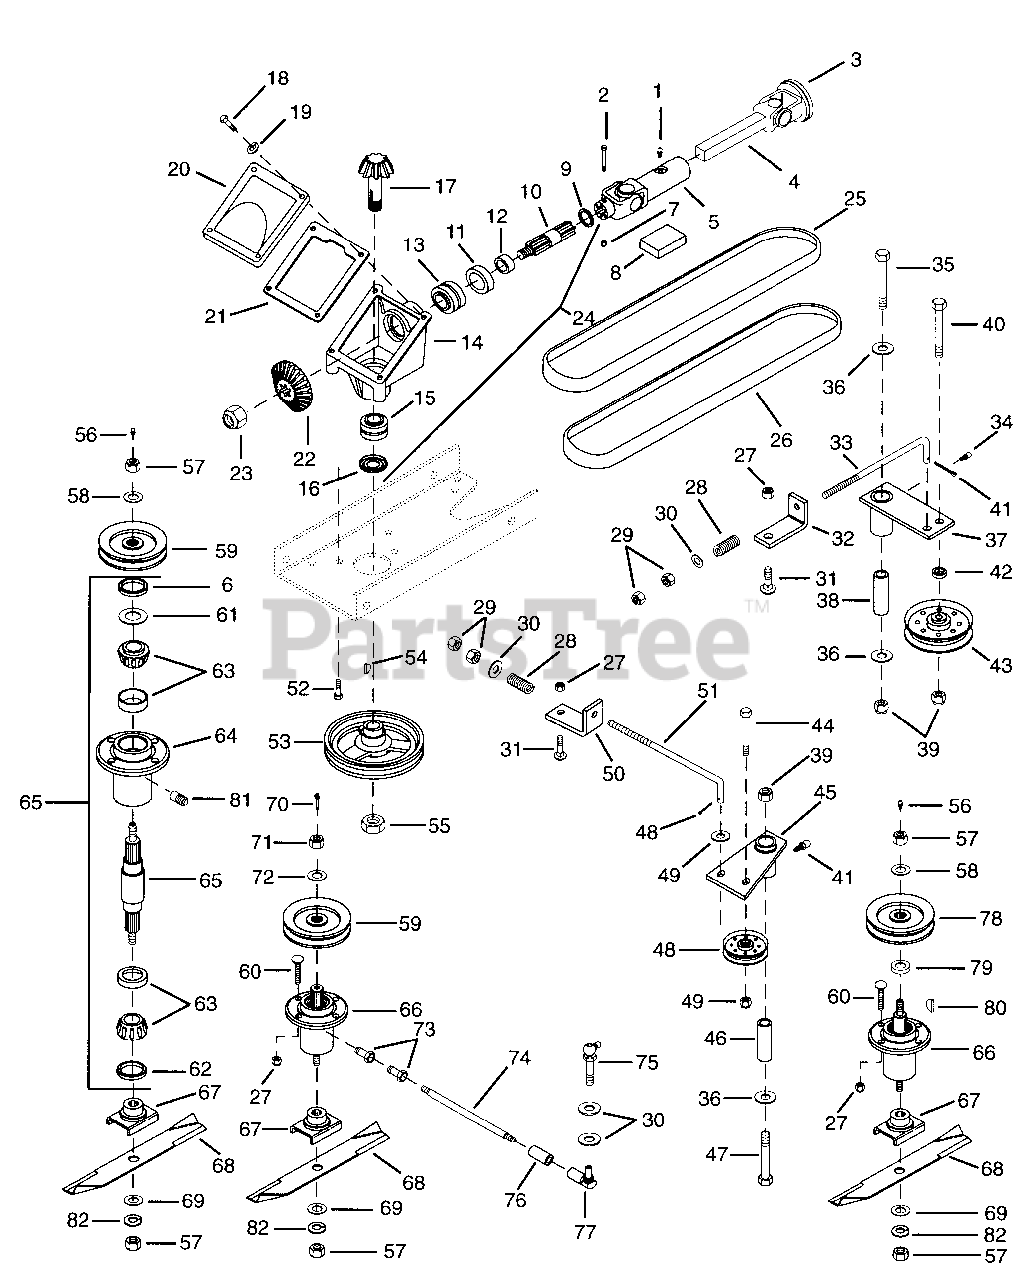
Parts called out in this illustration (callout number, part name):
1	Fitting-Lube .25-28 x .256
2	Bolt-Hex .25-20 x 2.25
3	Q.D. Yoke
4	Shaft, Drop Square Bar
5	Joint, U Female End
6	Seal 1.987 x 1.500 x .313
7	Nut-Locking-Nylon .250-20 Grade 2
8	Kit, Repair U-Joint
9	Ring-Retaining 1.106 x .95
10	Shaft
11	Seal 1.250 x 1.983 x .250
12	Bushing Flange 1.00 x 1.25 x 1.25
13	Bearing-Assembly 1.000 x 1.980 x 1.243
14	Casting, Gear Box
15	Bearing-Assembly .75 x 1.781 x 1.499
16	Seal 1.250 x 1.691 x .310
17	Shaft, Pinion Gear
18	Bolt-Hex .25-20 x .50 Grade 5
19	Washer Lock .250 Reg.
20	Cover, Gear Housing
21	Gasket, Gear Housing
22	Gear, Bevel
23	Nut-Locking-Nylon .75-10 Grade 2
24	Assembly, Drive 50" Mower
25	V-Belt A-Section 58.56 x .516
26	V-Belt 5L Section 70.375 x.438 x.660
27	Nut-Locking-Nylon .375-16 Grade 2
28	Spring-Compression .125 x .78 x 1.00
29	Nut-Hex .375-24 Grade 2
30	Washer-Flat-Steel .406 x .812 x .065
31	Bolt-Hex .375-16 x 1.00 Grade 5
32	Support, Spring "B"
33	Rod, Idler 50 In. Mower
34	Pin-Cotter .06 x 1.00
35	Bolt-Hex .50-13 x 3.75
36	Washer-Flat-Steel .500 x 1.250 x .083
37	Weldment, Idler Pivot "B"
38	Spacer .505 x .855 x 2.50
39	Nut-Locking-Nylon .50-13 Grade 5
40	Bolt-Hex .50-13 x 2.00 Grade 5
41	Fitting-Lube .25-28 x .46
42	Spacer .516 x .875 x .300
43	Idler-Flat-Pulley 6.75 x .510
44	Bolt-Hex .38-16 x 1.75 Grade 5
45	Weldment, Idler Pivot "A"
46	Spacer .562 x .855 x 2.18
47	Bolt-Round Head Square Neck .50-16 x 3.50
48	Pulley-Idler 4.50 x .380
49	Nut-Locking-Center .625-10 Grade 2
50	Support, Spring "A"
51	Rod, Idler 40 In. Mower
52	Bolt-Hex .50-13 x 1 Grade 5
53	Pulley, Gearbox
54	Key-Rectifier .313 x .275 x .932
55	Nut-Hex-Jam .750-10
56	Fitting-Lube 1/8
57	Nut-Hex .625-11 Grade 2
58	Washer-Flat-Steel .687 x 1.312 x .5150
60	Bolt-Round Head Square Neck .38-16 x 1.375
61	Washer-Flat-Steel .97 x 1.865 x .03
62	Seal 1.987 x 1.375 x .313
63	Assembly, Bearing Cup & Cone
64	Bearing Housing
65	Shaft, Spindle
66	Service Kit Spindle Assembly
67	Weldment, Blade Cradle
68	Blade
69	Washer-Flat-Steel .656 x 1.312 x .095
70	Bolt, Hex Spec 1/2-13 x 1.34
71	Washer-Lock .50 Reg.
72	Washer-Flat-Steel 1.38 x .562 x .109
73	Elbow, Street 1/8-27
74	Nipple, Pipe 6.30
75	Fitting, Lube 65 Deg.
76	Coupling-Pipe .12-27
77	Elbow, Adaptor 90 Degrees
79	Bearing-Needle .688
80	Key-Feather .25 x .875 x .312
81	Relief Fitting
82	Washer-Lock .625 x .156
